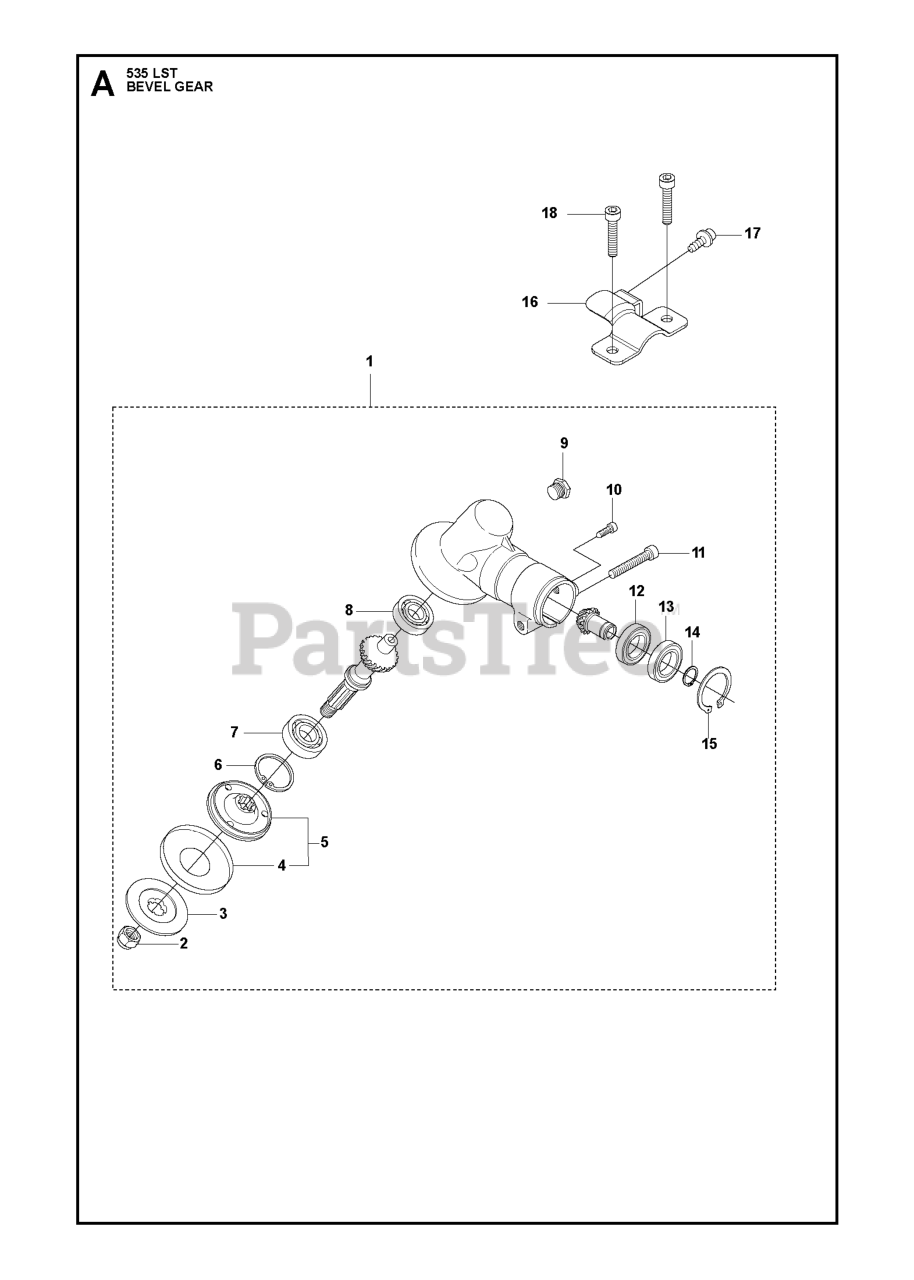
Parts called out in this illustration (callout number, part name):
1	BEVEL GEAR ASSY
2	GEARHEAD NUT - BRUSHCUTTER
3	SUPPORT FLANGE
4	WASHER
5	DRIVE DISC
6	RETAINING RING SGH 28
7	BEARING
8	BALL BEARING 8X22X7/608Z
12	BALL BEARING 24X9X1/609ZR
14	RETAINING RING
15	RETAINING RING
16	BRACKET SHIELD
18	SCREW IHSCM
